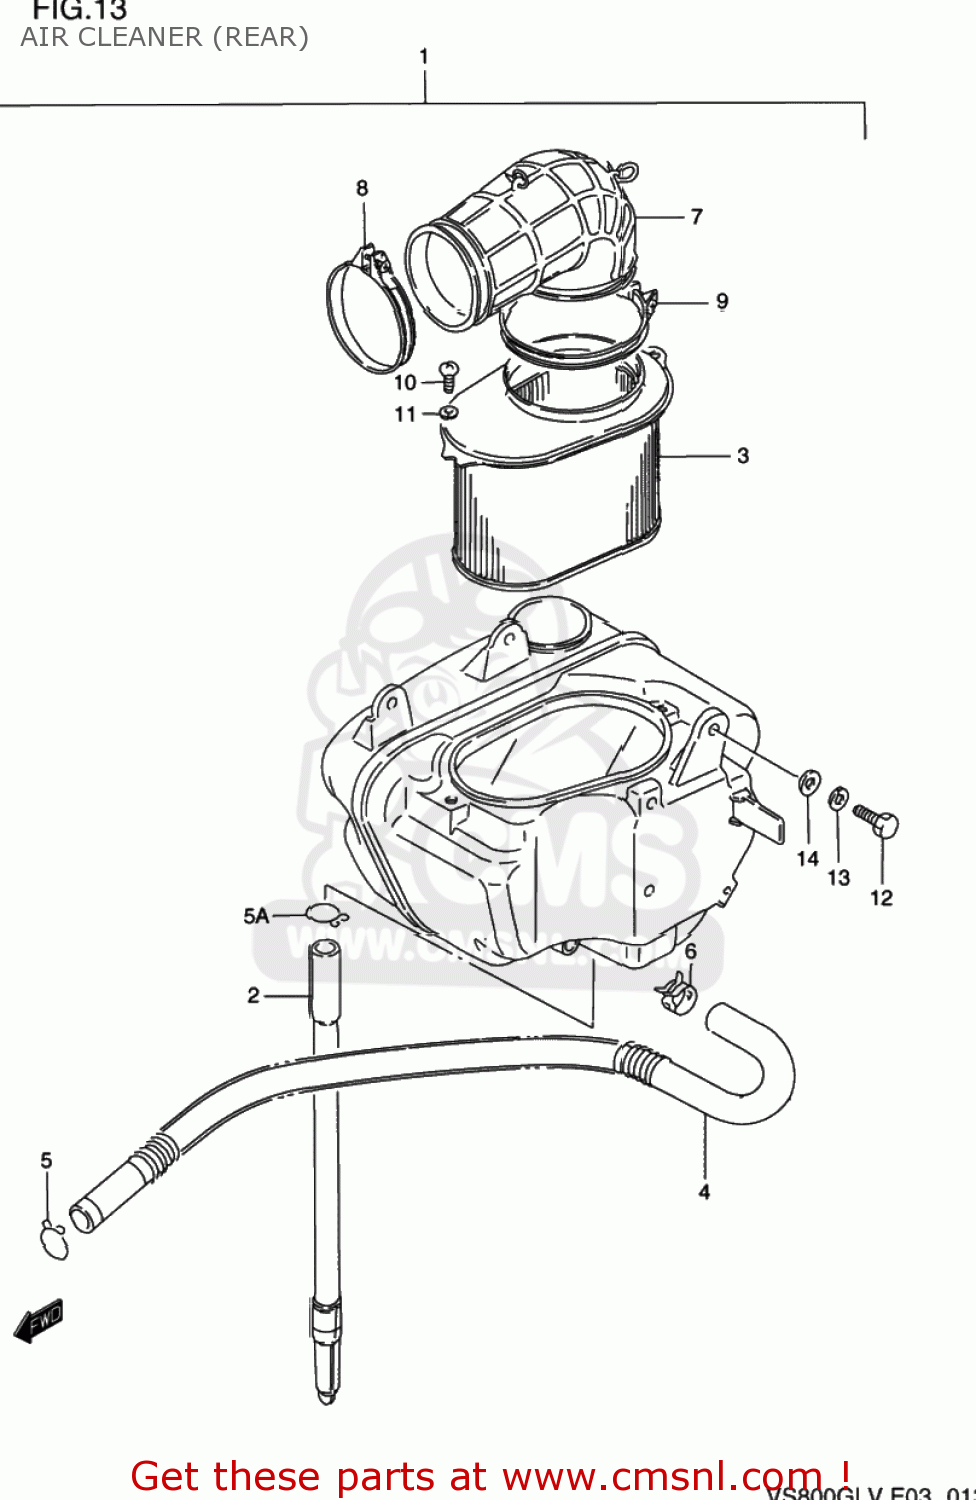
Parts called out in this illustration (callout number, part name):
1	CLEANER ASSY,AIR RR
2	DRAIN TUBE
3	FILTER ASSY
4	TUBE SET,BREATHER
5	CLIP
5A	CLIP
6	CLIP
7	TUBE,AIR CLEANER OUTLET
8	CLAMP
9	CLAMP
10	SCREW
11	WASHER,LOCK
12	BOLT
13	WASHER,LOCK
14	WASHER(6.5X16X1.2)
